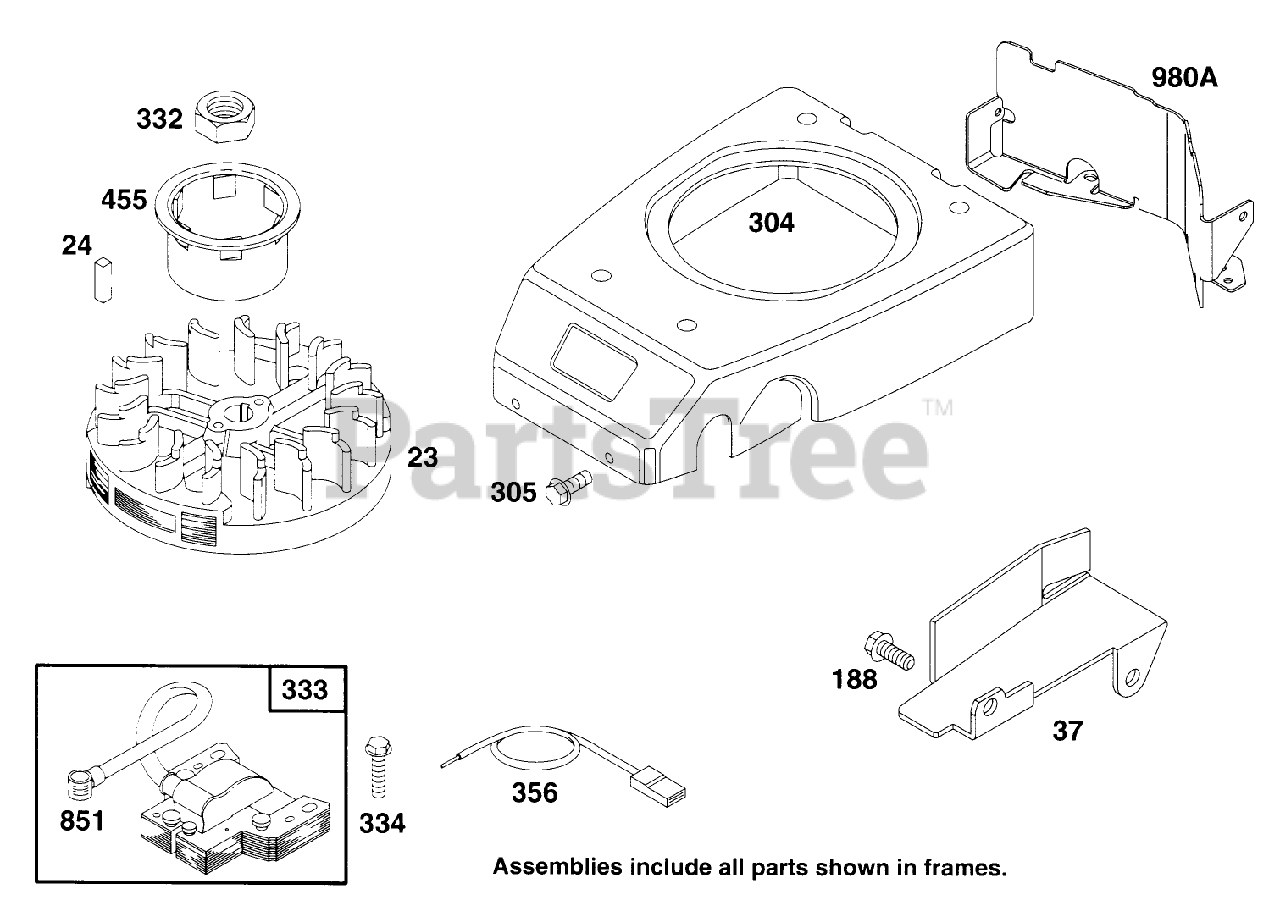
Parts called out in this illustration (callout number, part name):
24	KEY - FLYWHEEL
188	SCREW - SEM
304	BLOWER HSG ASM
305	SCREW - HEX HEAD
332	NUT - HEXAGON
356	WIRE - GROUND
980A	BLOWER HSG BRACKET
